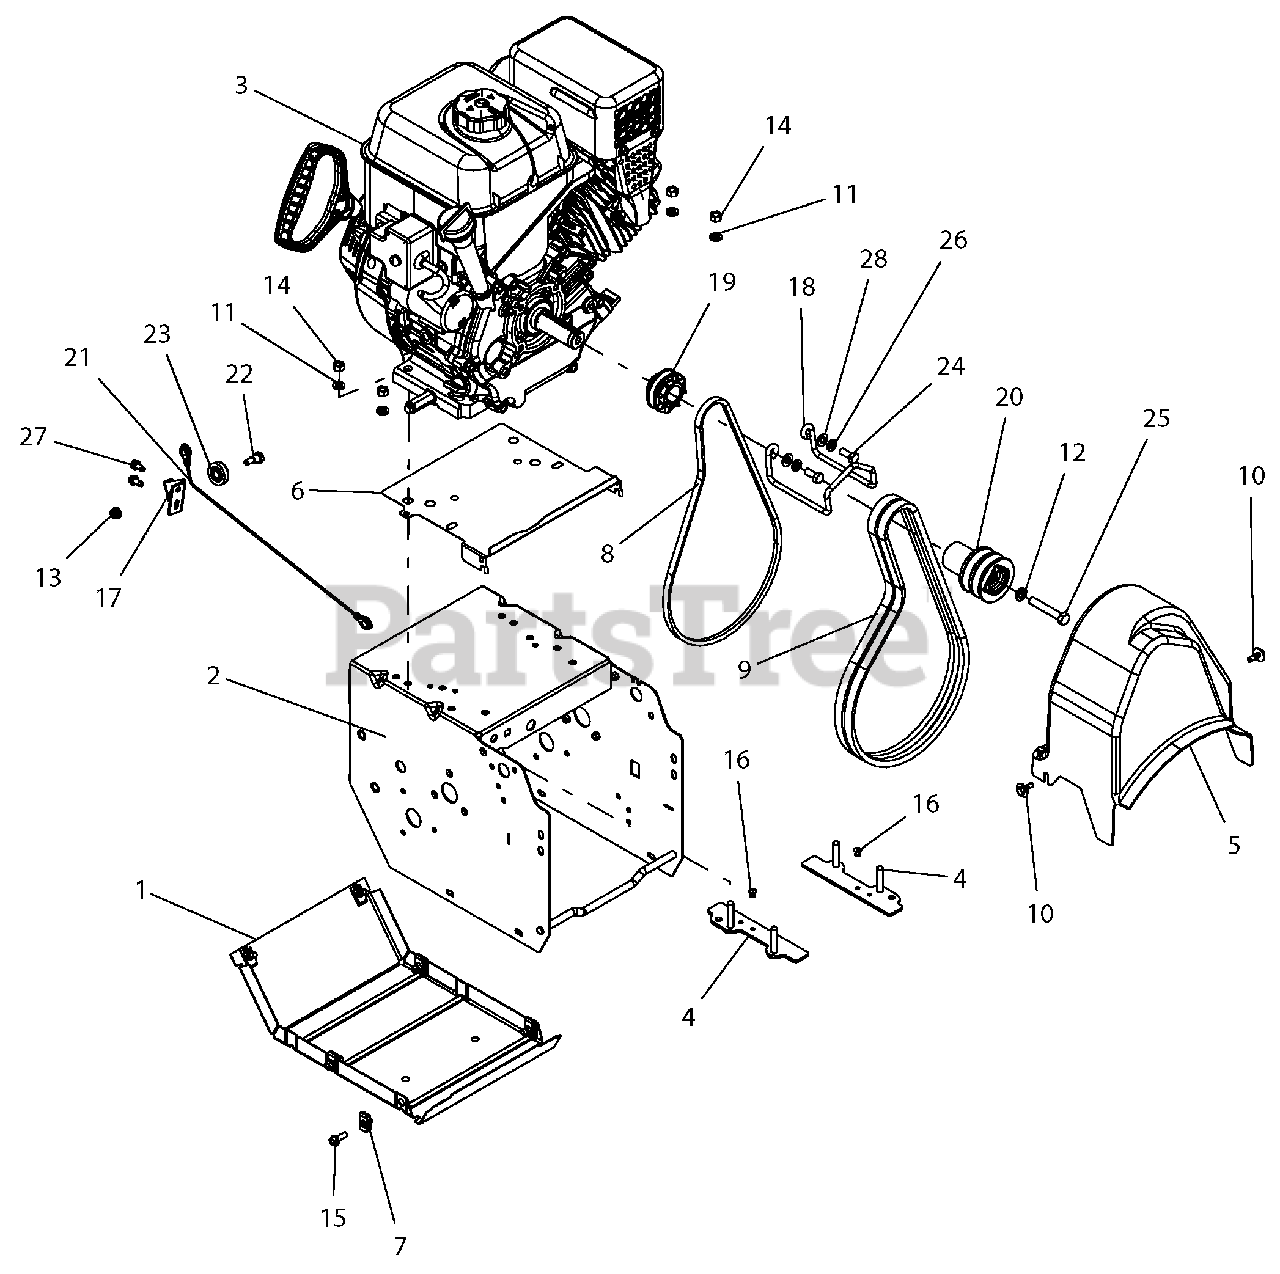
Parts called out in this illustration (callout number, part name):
1	COVER, BOTTOM
2	WELDMENT, FRAME - DELUXE 16"
3	ENGINE, ARIENS AX291 120V/60W
3	ENGINE, ARIENS AX414 120V/60W
4	STRAP,ENGINE BOLT,ARIENS MED
5	BELT COVER
6	BAFFLE,ENGINE,ARIENS MED BLOCK
7	NUT-RTNR .25-20X.56
8	V-BELT, 3L-WRAPPED
9	V-BELT, HA-RAW EDGE (SET)
10	SCR-TAP .25-20X.5 CAPTIVE
11	WSHR-LK .312X.097 HVY YWZC
12	@WSHR-LK .38X.094 REG YWZC
13	@NUT-LK-CTR-FLG .25-20 YWZC
14	@NUT-HEX .31-18 YWZC
15	BLT-HEX .25-20X.75 HWH YZ GR5
16	RVT-POP .187 YZ
17	BRACKET, CABLE PULLEY
18	FINGER, BELT
19	SHEAVE, DRIVE
20	SHEAVE,ATTACHMENT 2-GRV
21	CABLE, LOWER TRACTION (DELUXE)
22	BOLT, SHLDR-.375X.375X.25-20
23	PULLEY, CABLE
24	BLT-HEX .31-24X.75 YWZC GR5
25	BLT-HEX .38-24X2.25 YWZC GR5
26	WSHR-LK .312X.097 HVY YWZC
27	SCR-TAP .25-20X.50 HWH TR YWZ
28	@WSHR-FL-STL.344X.688X.065YWZC
